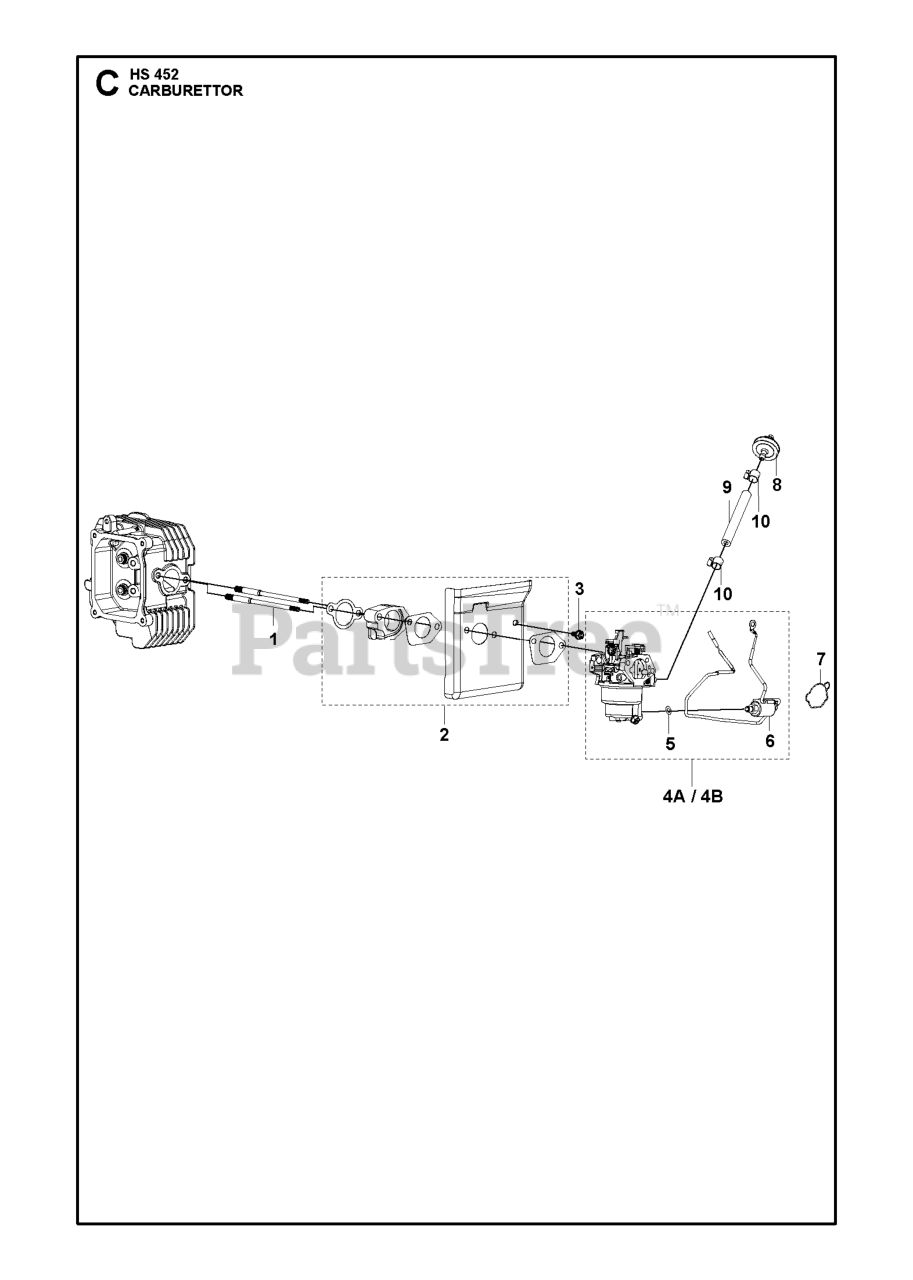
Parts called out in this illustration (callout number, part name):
1	STUD T381: M6/8 L=141
2	GASKET KIT CARBURETTOR GASKET
3	BOLT GB/T 5789: M6 L=12
4A	CARBURETOR
6	SOLENOID SOLENOID VALVE
7	GASKET CARBURETTOR GASKET
8	FILTER FUEL.FILTER (ENG.452)
10	CLIP HOSE CLIP
